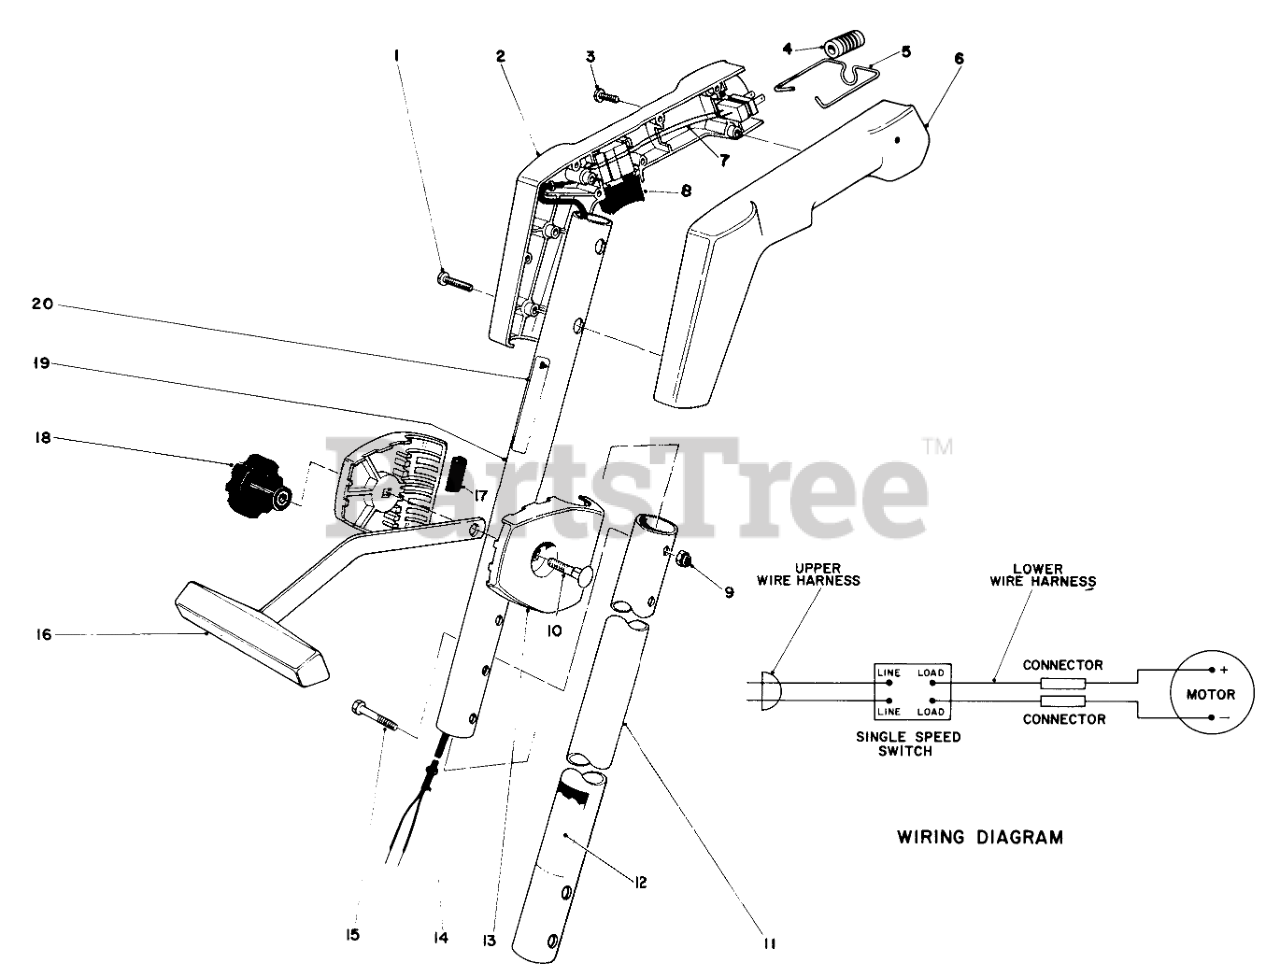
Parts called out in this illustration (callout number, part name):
2	Right Hand Grip
3	SCREW-PPH
4	RETAINER EXT. LORD
5	Extension Cord Wire Clamp
6	Left Hand Grip
7	WIRING HARNESS UPPER
8	SWITCH SINGLE SPEED
9	NUT-LOCK, NI
10	BOLT-CARR
11	Lower Tubing
12	REP. SERIAL PLT
13	T-HANDLE BRKT(RED)
14	WIRING HARNESS STD
15	Screw
16	Tee Handle
17	RUBBER INSERT
19	Upper Tubing
20	Caution Decal
